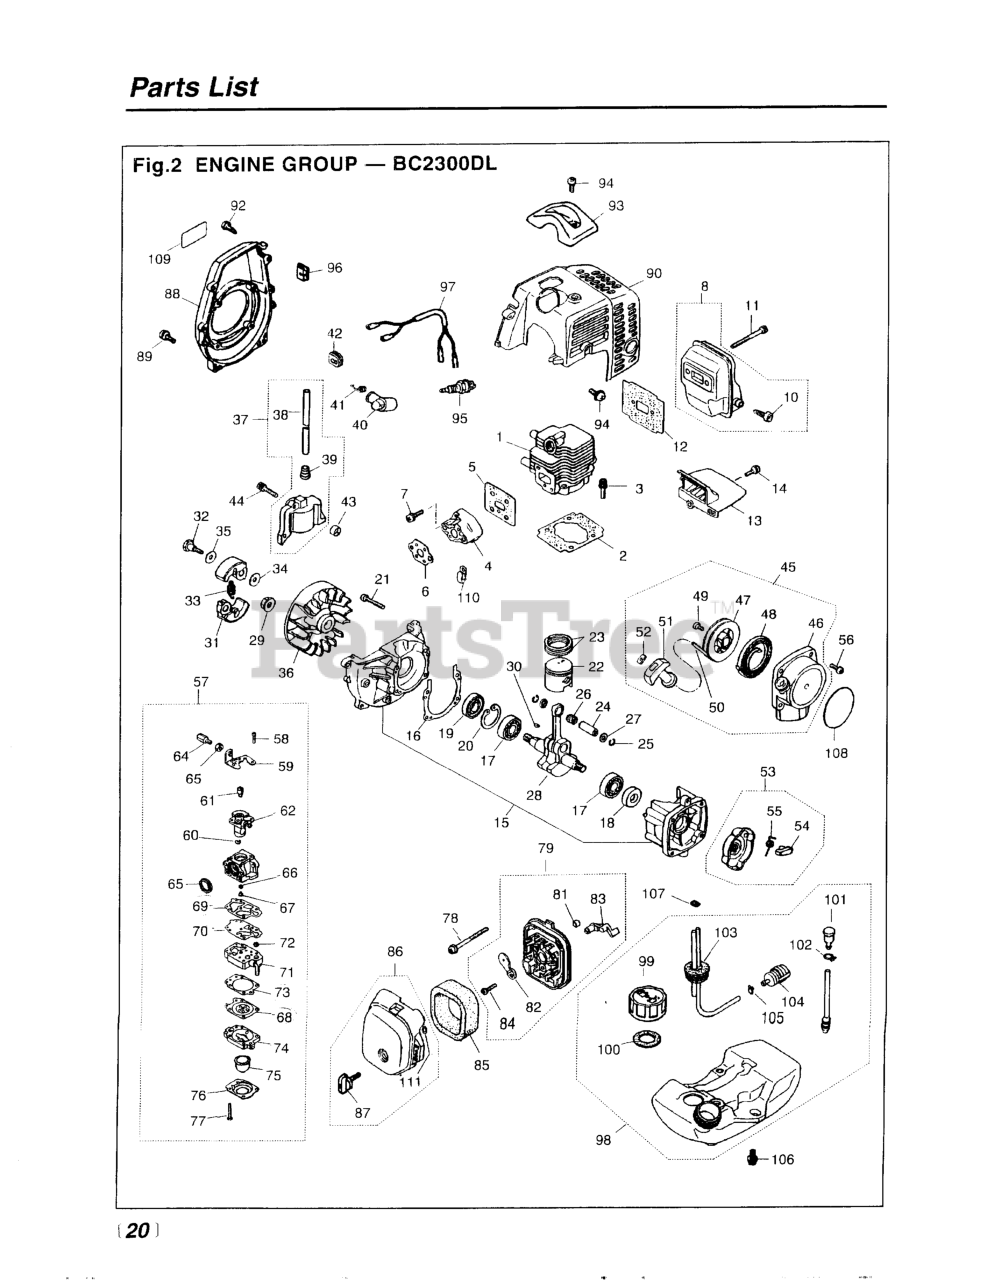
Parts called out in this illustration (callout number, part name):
1	CYLINDER
3	BOLT, M5 X 22
7	SCREW, M5X20 (RPLS.1400-75510)
8	MUFFLER ASSY (RPLS 5501- )
10	ARRESTER (RPLS 5850-15140)
11	BOLT, M5 x 50
12	GASKET, MUFFLER
14	SCREW, M4 X 16
15	CRANKCASE
17	BEARING
18	SEAL, OIL (RPLS 1100-21210)
19	SEAL, OIL (RPLS 1140-21220)
20	RING, SNAP, M28 x 1.2
21	BOLT, M5 X 30
22	PISTON (REPLACES 1140-41110)
23	RING, PISTON (RPLS 1850-41210)
24	PIN, PISTON 5x8x26
25	RING, SNAP (RPLS 1101-41320)
27	WASHER
28	CRANKSHAFT (RPLS 1850-42000)
30	KEY
32	BOLT
33	SPRING, CLUTCH (RPLS-51220)
34	WASHER, FLAT (USE 182303)
37	COIL ASSY (RPLS 5500-71200)
38	CORD
39	CAP
41	SPRING
42	GROMMET
43	SPACER (RPLS -71260)
44	BOLT
45	RECOIL ASSEMBLY
46	CASE
47	REEL
48	SPRING, SPIRAL
49	SCREW (RPLS -75150)
51	KNOB
52	PLATE, STOPPER
53	PULLEY ASSY (RPLS -75210)
54	RATCHET (RPLS 1850-75220)
55	SPRING, RETURN
56	SCREW, M4 X 16
57	CARBURETOR
58	SCREW
60	RING
61	SWIVEL
62	VALVE ASSY
63	SCREW, CABLE ADJUSTER
64	NUT, CABLE ADJUSTER
65	RING, PACKING
66	RING, O
67	JET
68	DIAPHRAGM (USE 4810-81260)
69	GASKET, PUMP
70	DIAPHRAGM
71	BODY, PUMP
73	GASKET, DIAPHRAGM
74	BODY, PURGE
75	PUMP, PRIMING
76	COVER, PUMP
77	SCREW
78	SCREW, M5 x 60
79	BODY-A (RPLS -82101)
81	SLEEVE
82	PLATE, CHOKE (RPLS-82130)
83	LEVER, CHOKE
84	SCREW (REPLACES 50030272)
85	ELEMENT
87	KNOB (RPLS -82220)
88	COVER, FAN (RPLS-31110)
89	SCREW, M5X20 (RPLS.1400-75510)
91	SCREW, M5 x 12
92	SCREW, HOUSING
93	GUARD, PLUG
94	SCREW,M5 X 14 (RPLS 1400-15510
97	CORD COMP (RPLS -73200)
99	CAP (RPLS -85200)
100	PACKING
102	CLIP
103	PIPE COMPLETE
104	FILTER (RPLS 1850-85300)
105	CLIP (REPLACES 2841-31280)
106	SCREW
107	CLIP
108	LABEL, RECOIL (RPLS -91121)
110	CLAMP
111	RING
